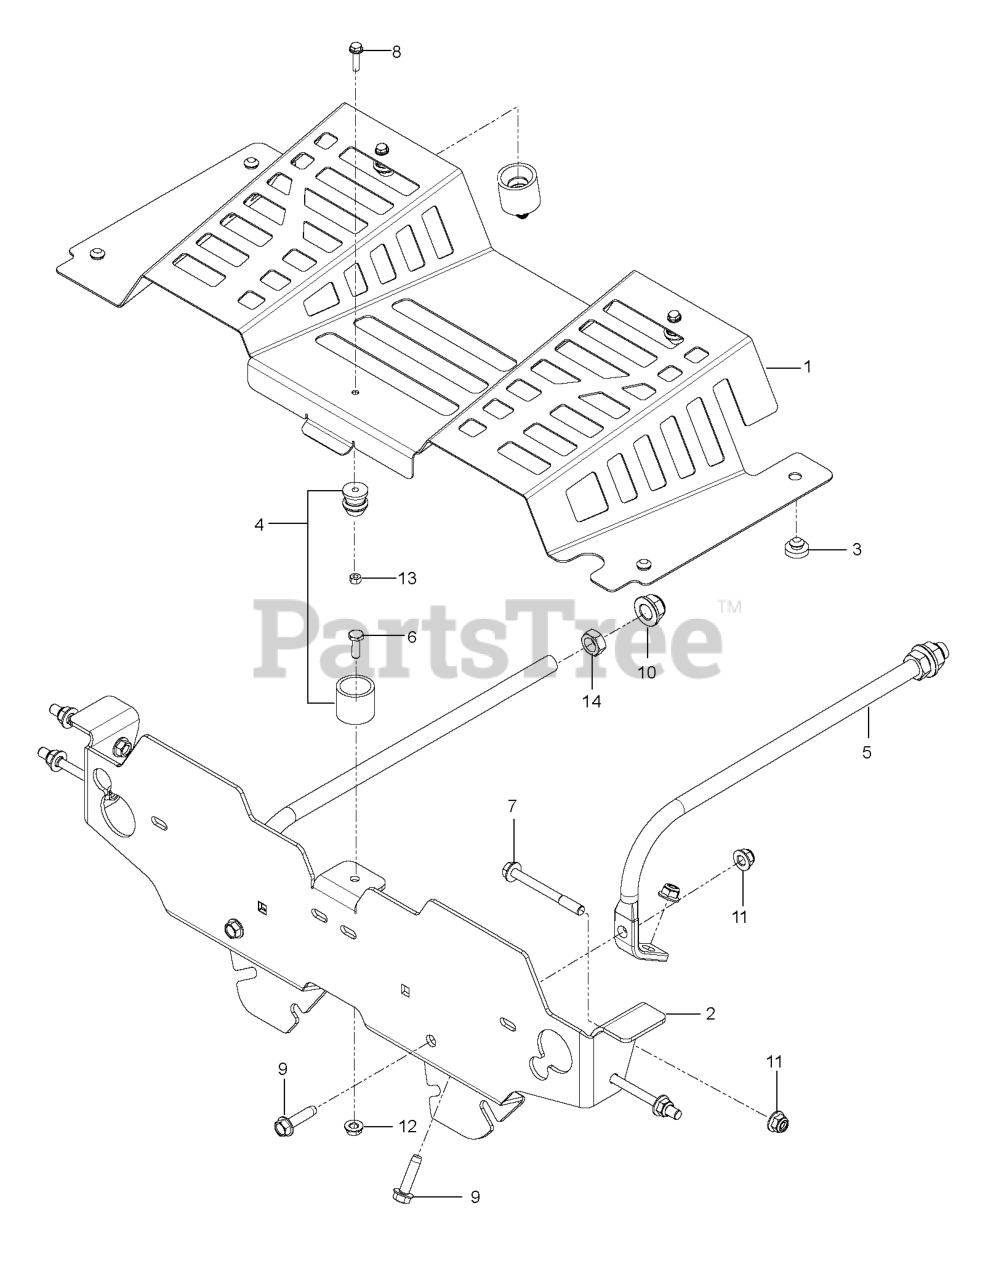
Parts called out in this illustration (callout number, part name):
1	SHIELD.FAN.W/DECALS
2	BRACKET ANCHOR CABLE ORANGE X6
3	GROMMET, BUMPER
4	HOLDER.ASM.STEM.BASE.WASHER
5	ROD.CROSS.MEMBER.ANVH.CAB.YZIN
6	BOLT
7	BOLT HEX FLGHD 5/16-18X3 GR. 5
8	SCREW M6SF 5X20
9	SCREW.THDROL.5/16-18X1.25.TYTT
10	NUT, 1/2-13 HEX FLG NYLOC ZD
11	5/16-18 NYLOC FLANGE NUT
12	NUT.HEX.FLANGE.1/4
13	NUT M6M M5
14	NUT.HEX.JAM.1/2-13
